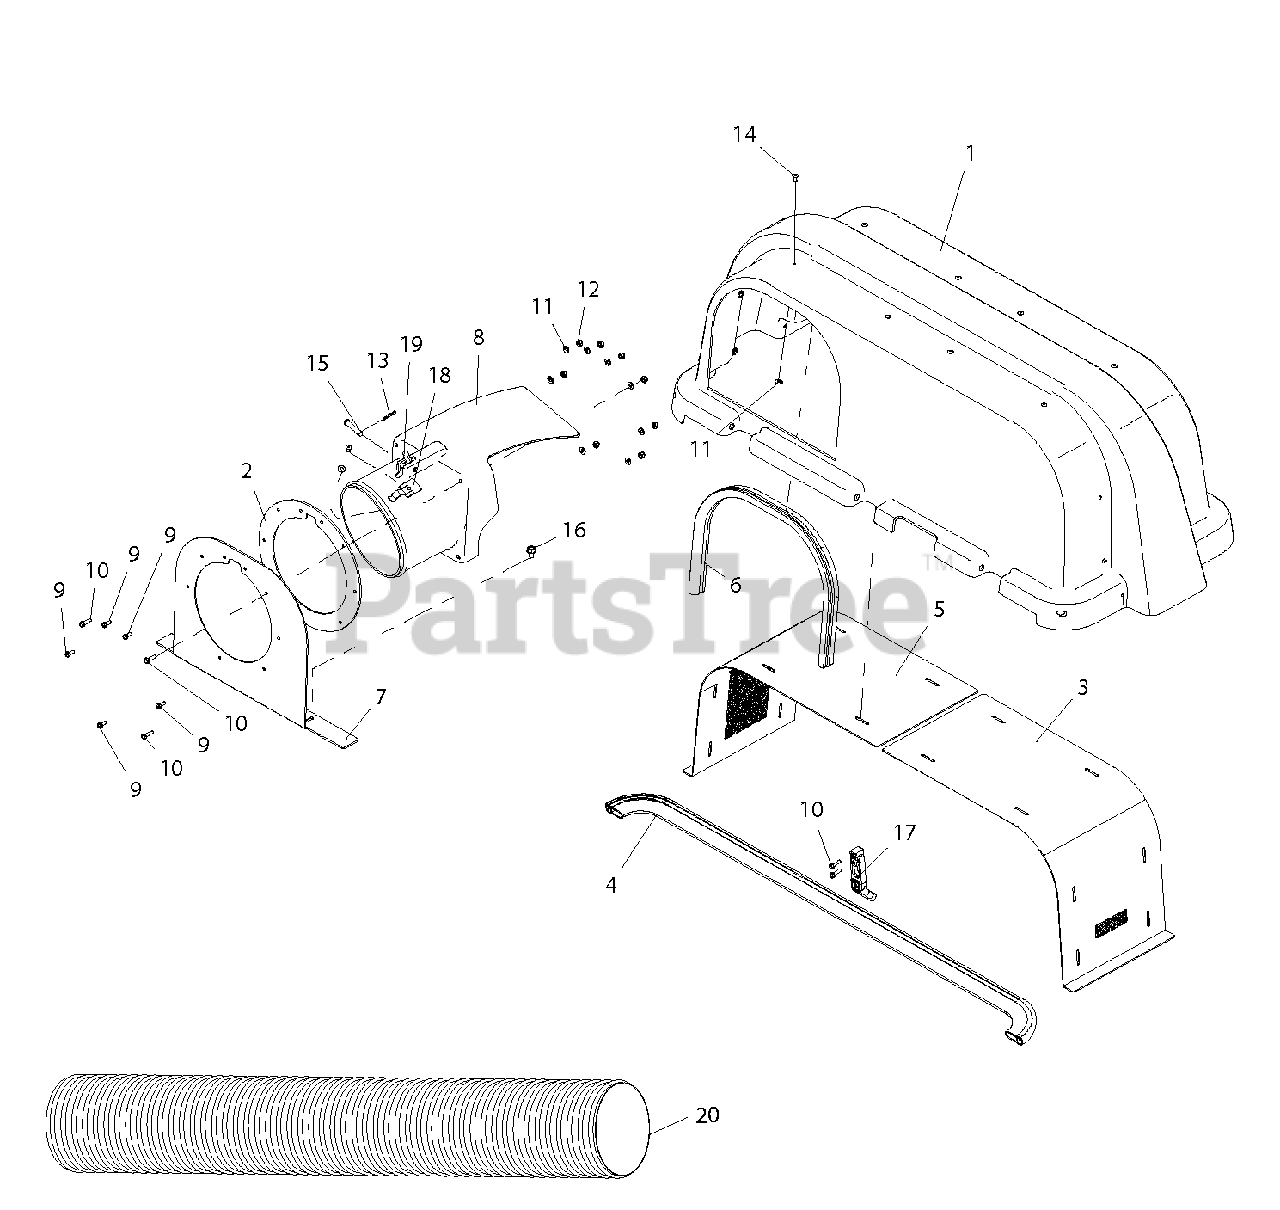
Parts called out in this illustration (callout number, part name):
1	COVER, 2-BUCKET BAGGER
2	SEAL, UPPER BOOT
3	WLDMT, BAGGER HOOD VENT, LH
4	SEAL, BULB-BAGGER HOOD
5	WLDMT, BAGGER HOOD VENT, RH
6	SEAL, BULB
7	WLDMT, TUBE SUPPORT
8	BOOT, UPPER
9	SCR-MCH 10-24X.50 HWH YWZC
10	SCR-MCH 10-24X.75 HWH YWZC
11	WSHR-FL-STL
12	NUT-LK-NYL #10-24 YWZC
13	PIN-HAIR, ENDRIES #25 YWZC
14	RVT-POP .187X.375
15	PIN, CLEV .309X1.62 YWZC
16	SCR-TAP .31-18X.50 HWH TR TWZ
17	LATCH, RUBBER
18	LATCH, THUMB
19	INDICATOR, FLOW
20	BAGGER TUBE (815040)
